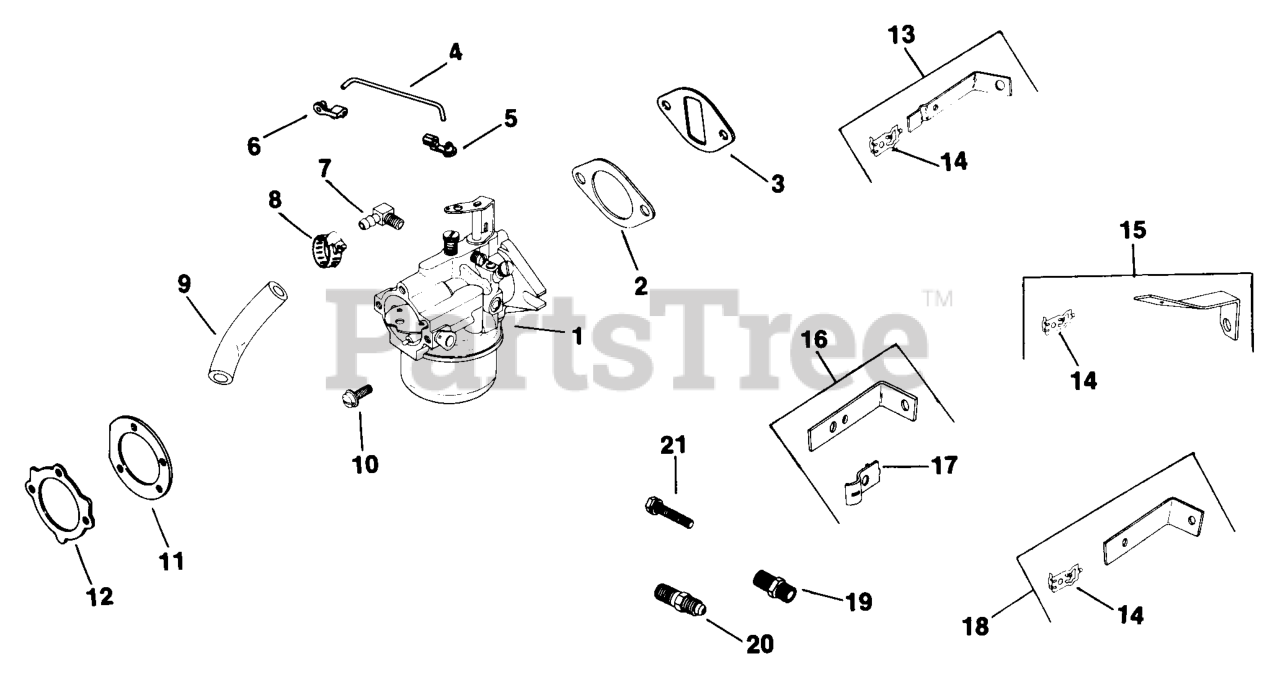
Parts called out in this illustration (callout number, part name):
1	CARBURETOR - USE 47 853 04
1	CARBURETOR - USE 47 853 30
1	KIT, CARBURETOR W/LINKAGE - DISCONTINUED
3	GASKET, CARBURETOR
6	BUSHING - USE 25 158 11
7	CONNECTOR, 90 DEG. HOSE
8	CLAMP, HOSE 1/2" USE 25 237 14-S
9	LINE, FLEXIBLE FUEL - DISCONTINUED
10	SCREW, SLT HD 5/16-18X1" - DISCONTINUED
